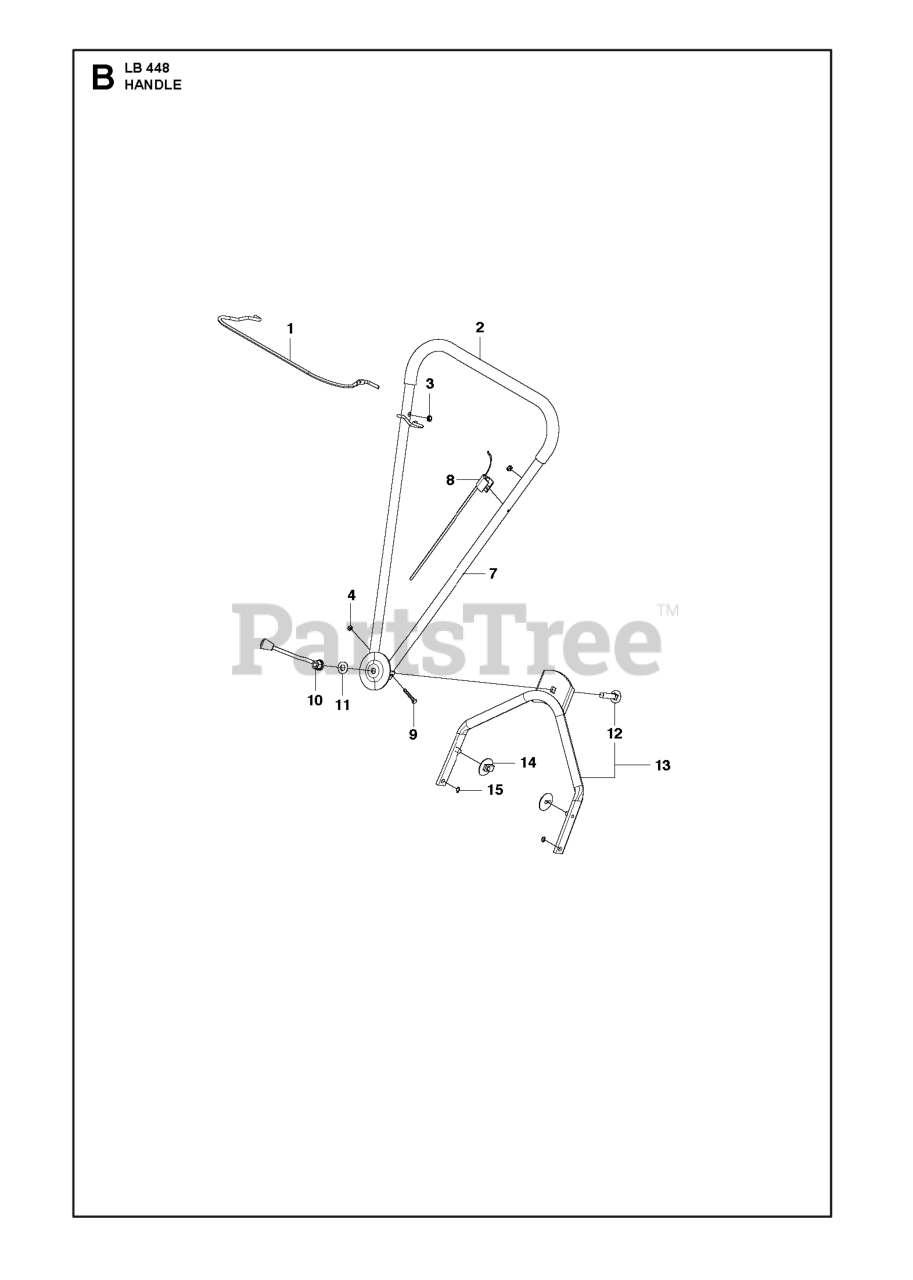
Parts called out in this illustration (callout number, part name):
4	NUT FLANGE - M6
9	Hex Head Capscrew, M6 X 1.00 X 40MM
15	RETAINING RING SGA 10
